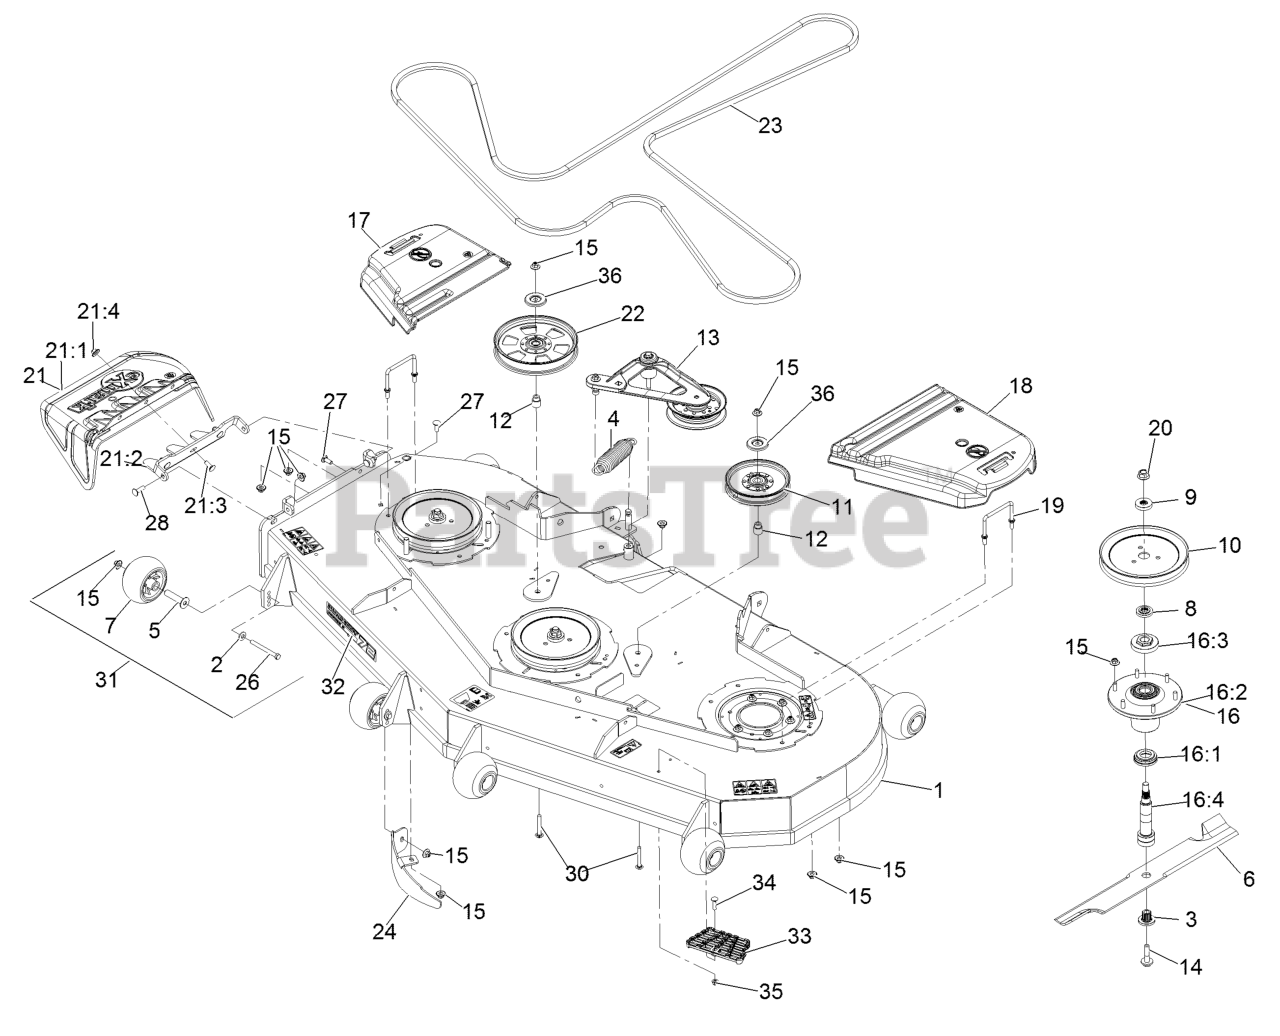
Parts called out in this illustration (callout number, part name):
1	ASM,Deck W/Decals 724
2	Washer-Belleville
3	Bushing, Splined
4	Spring-Extension
5	Axle, Roller
6	Blade, Solid (72")
6	Blade, Low Lift (72")
6	Blade, Mulching (72")
6	Blade, Notched (72")
6	Blade-Extreme 2, 24.50"
7	Roller-Anti-Scalp
8	Spacer, Splined Stepped
9	Spacer, Splined
10	Sheave,Blade Drive 9.00
11	Idler-Pulley
12	Bushing, Idler
13	Deck Idler ASM
14	Screw-Sems 1/2-20 X 2.19
15	Nut-Nyloc 3/8-16 Flg
16	ASM,Spindle Housing
16:1	Guard, Bottom
16:2	Asm, Cutter Housing
16:3	Nut, Spindle 7/8-14
16:4	Spindle,Double Spline
17	Cover-Belt, RH
18	Cover-Belt, LH
19	Wireform-Cover
20	Nut-Flange 5/8-18 Centerlock
21	ASM,Discharge Chute
21:1	Chute, Discharge
21:2	Bracket,Discharge Chute
21:3	Bolt-Carriage 3/8-16 X 1
21:4	Nut-Nyloc 3/8-16 Flg
22	Pulley-Idler, Flat
23	Belt-V
24	Baffle-Dogleg, Lz72
26	Screw-HH
27	Bolt-Carriage 3/8-16 X 1
28	Bolt-Carriage 3/8-16 X 1 1/4
30	Screw-CARR
31	Kit, Anti-Scalp Roller
32	Decal, 726
33	Step-Deck
34	Bolt-Carriage 5/16-18 X 1 1/4
35	Nut-Nyloc 5/16-18 Flg
36	Shield-Dust
